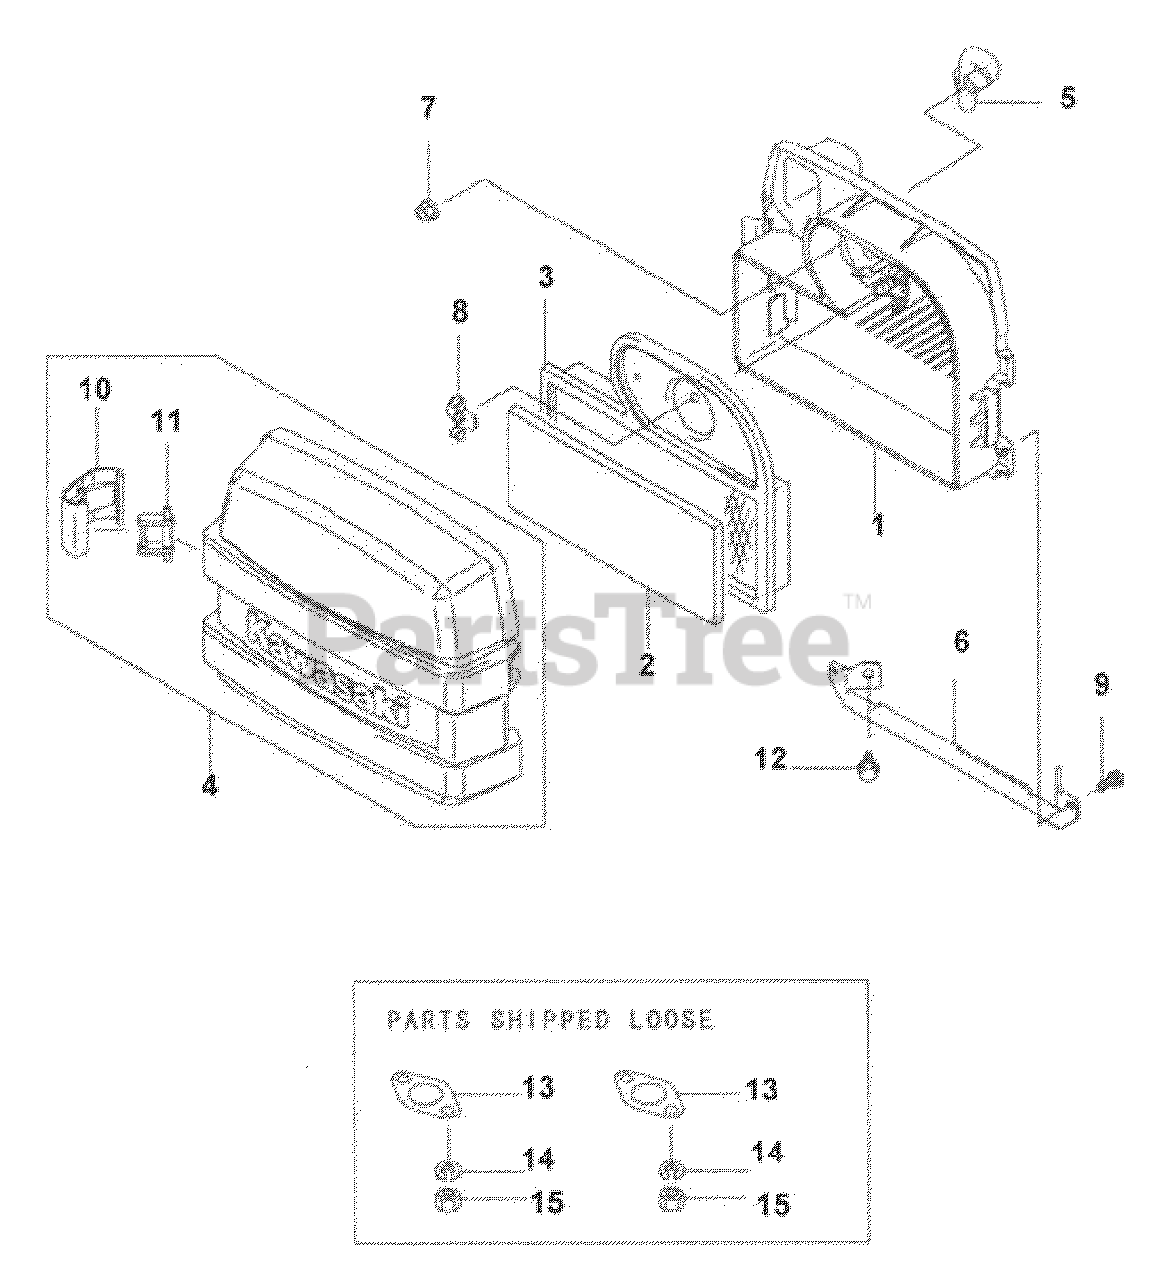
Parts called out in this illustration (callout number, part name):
1	Air Filter Case
2	Pre Filter
4	Air Filter Cover
7	Nut
9	Pan Screw
10	Air Filter Hook
12	Flange Bolt
13	Muffler Gasket
14	Lock Washer
